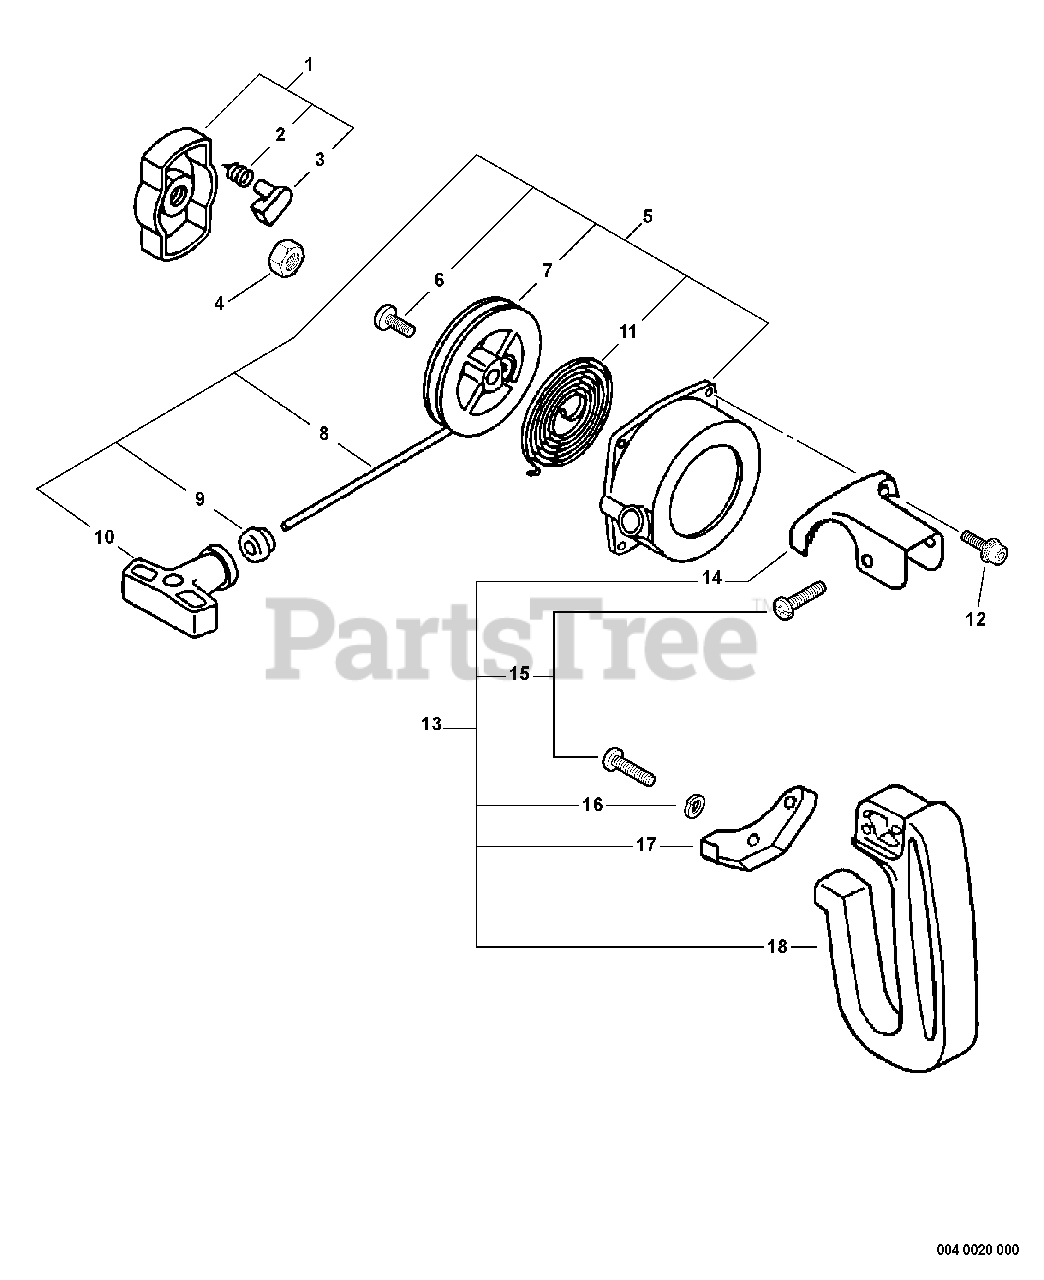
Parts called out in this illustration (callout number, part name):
1	PAWL ASSY, STARTER
2	SPRING, RETURN
3	PAWL, STARTER - BLACK
5	STARTER ASSY, RECOIL
6	SCREW
7	REEL, ROPE
8	ROPE, STARTER 3.0×1000
9	GUIDE, ROPE
10	GRIP, STARTER
11	SPRING, RECOIL
12	BOLT 4×16
13	HANDLE ASSY, SIDE
14	BRACKET, UPPER HANDLE
15	SCREW 5×16
16	WASHER, SPRING 5
17	BRACKET, LOWER HANDLE
